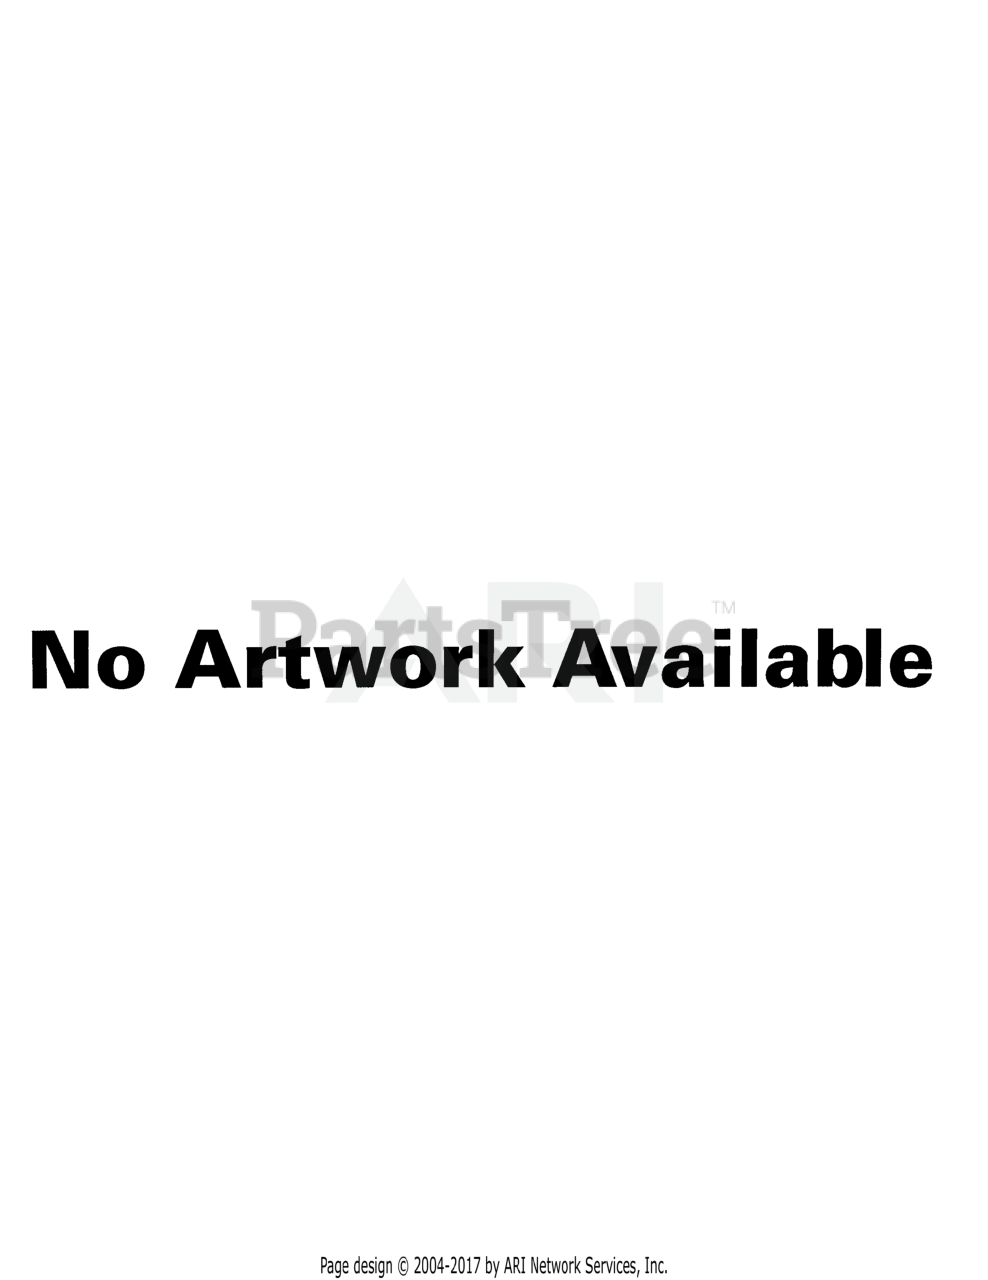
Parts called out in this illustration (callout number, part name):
1	BULK PIPE - 3x5 MM BLACK (4 PIECESx2 M)
2	BULK PIPE - 3x6 MM BLACK (4 PIECESx2 M)
3	BULK PIPE - 3x7 MM BLACK (4 PIECESx2 M)
4	BULK PIPE - 3x6 MM CLEAR (4 PIECESx2 M)
5	BULK PIPE - 2x4 MM CLEAR (4 PIECESx2 M)
